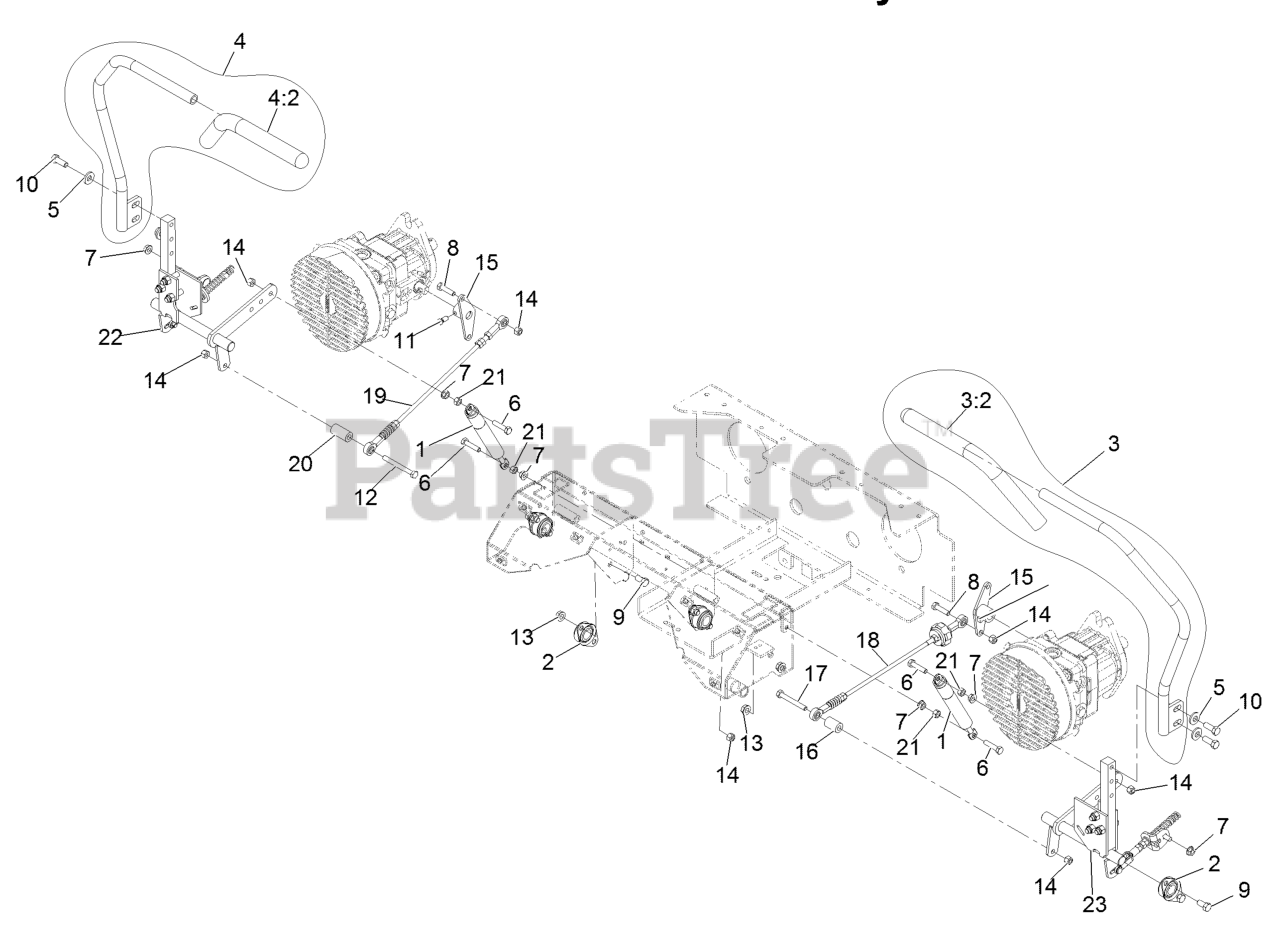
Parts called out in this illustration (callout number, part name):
1	DAMPER-CONTROL, MOTION
2	BEARING-FLANGE, SIDE
3	ASM,LH LEVER/GRIP
3:2	GRIP,CONTROL LEVER
4	ASM.RH LEVER/GRIP
4:2	GRIP,CONTROL LEVER
5	WASHER-BELLEVILLE
6	SCREW-HH
8	SCREW-HH
9	SCREW-HH
10	SCREW-HH
11	SCREW-SET
12	SCREW-HH
13	NUT-HHF, WHIZ
14	NUT-LOCK, NI
15	ARM-CONTROL, HYDRO
16	SPACER-HYDRO CONTROL, LH
17	SCREW-HH
18	TRACKING ROD ASM
19	RH HYD CONNECT LINK ASM
20	SPACER-CONTROL, HYD
21	NUT-HEX
22	RH MOTION CONTROL ASM
23	LH MOTION CONTROL ASM
